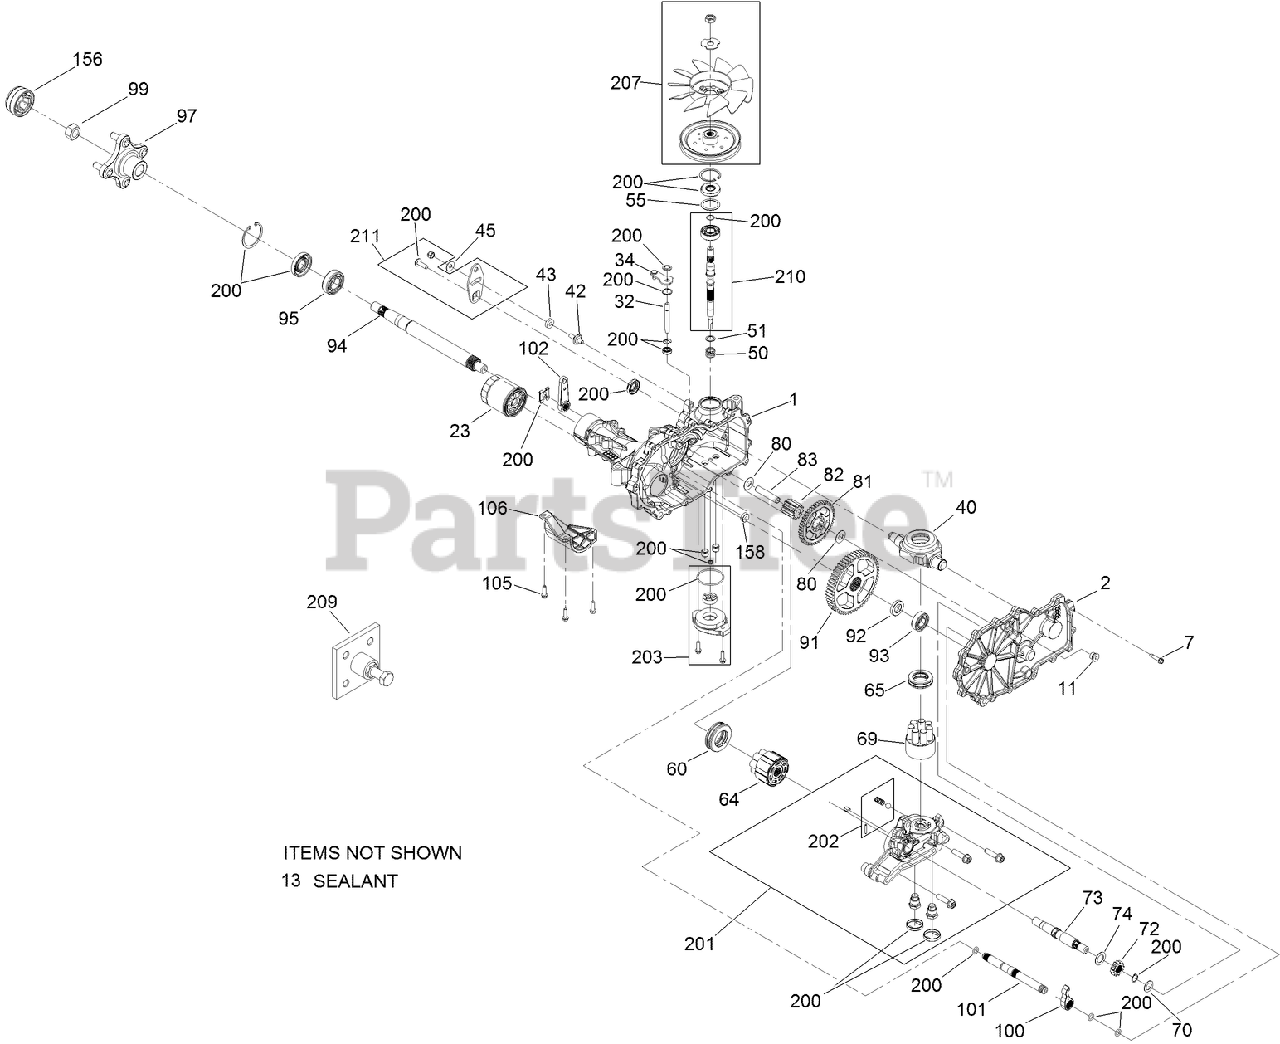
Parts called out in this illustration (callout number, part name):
1	LH MAIN HOUSING KIT
2	LH SIDE COVER KIT
7	SCREW-HHF
11	PLUG-THREAD, STRAIGHT
13	SEALANT
23	ELEMENT-OIL FILTER, HYD
32	ROD-BYPASS
34	ARM-BYPASS
40	SWASHPLATE-TRUNNION
43	PUCK-FRICTION
45	WASHER
50	SPRING-COMPRESSION
51	WASHER
55	SPACER
60	BEARING-THRUST
64	MOTOR CYLINDER BLOCK KIT
65	BEARING-THRUST, PLASTIC CAGE
69	7 PISTON BLOCK ASM
70	WASHER-FLAT
72	GEAR-13T
73	SHAFT-MOTOR
74	WASHER
80	WASHER
81	GEAR-46T
82	GEAR-11T
83	PIN-JACKSHAFT
91	GEAR-54T
92	SPACER
93	BEARING-BALL
94	SHAFT-AXLE
95	BEARING-BALL
97	HUB KIT
99	NUT-HUB
100	PAWL-BRAKE
101	SHAFT-BRAKE, INBOARD
102	HANDLE-BRAKE
105	SCREW-HF
106	GUARD-FILTER, LH
156	COVER-NUT, AXLE
158	MAGNET-RING
200	SEAL KIT
201	LH CENTER SECTION KIT
202	CHARGE RELIEF KIT
203	CHARGE PUMP KIT
207	FAN AND PULLEY KIT
209	PULLER-HUB, 4 BOLT
210	INPUT SHAFT KIT
211	CONTROL ARM KIT
